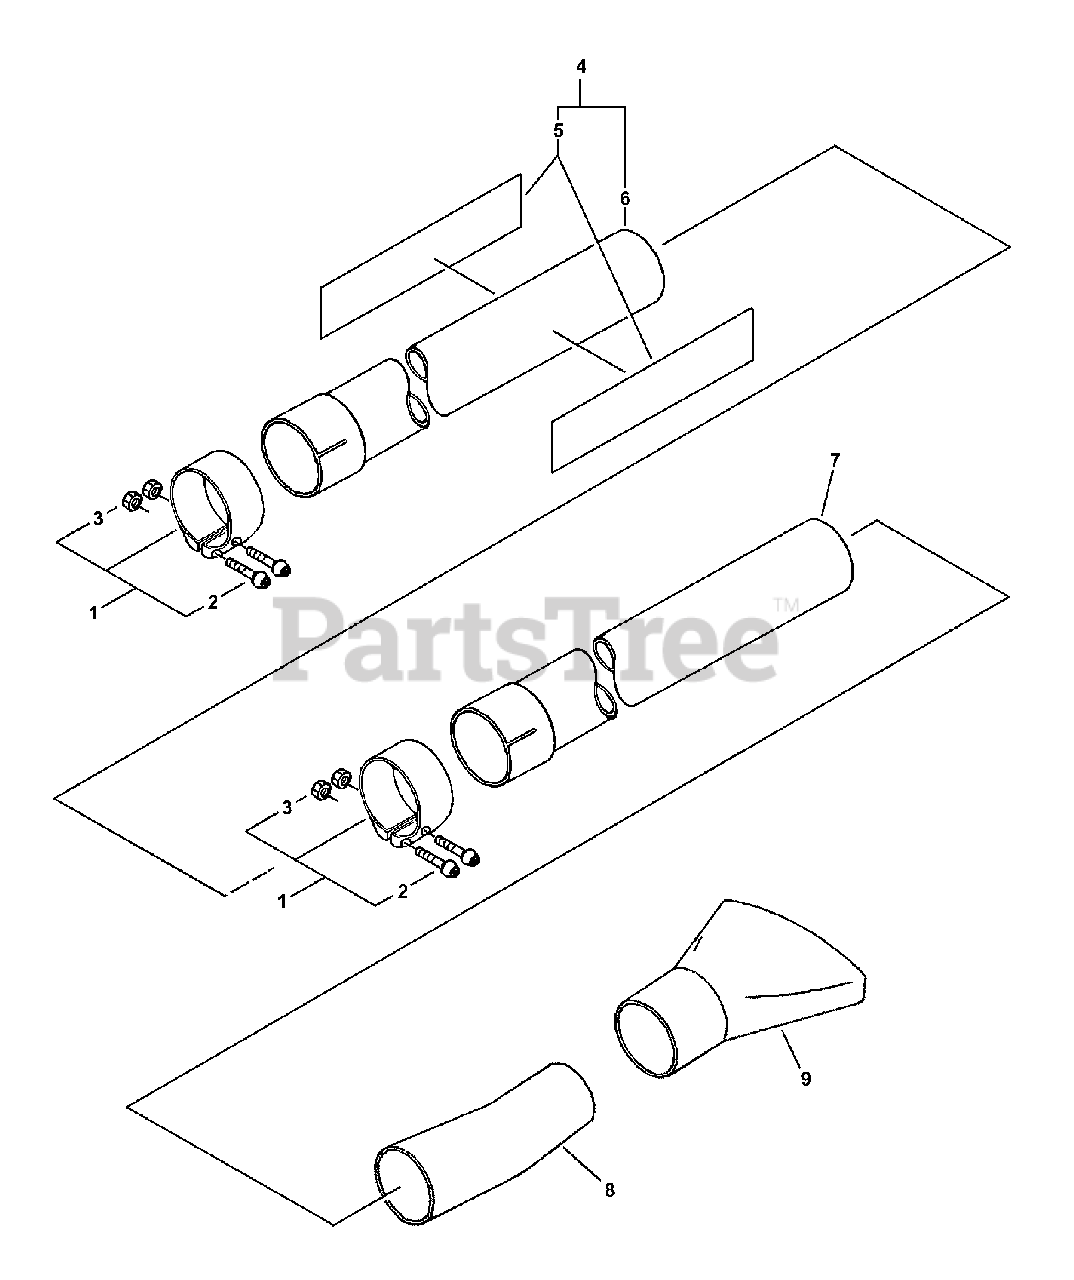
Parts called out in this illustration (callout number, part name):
1	CLAMP KIT
2	SCREW - 4X25
4	BLOWER TUBE KIT - STRAIGHT
5	LABEL - ECHO
6	TUBE, BLOWER - STRAIGHT
7	TUBE, BLOWER - STRAIGHT
8	TUBE, BLOWER - CURVED
9	NOZZLE - FAN HEAD
